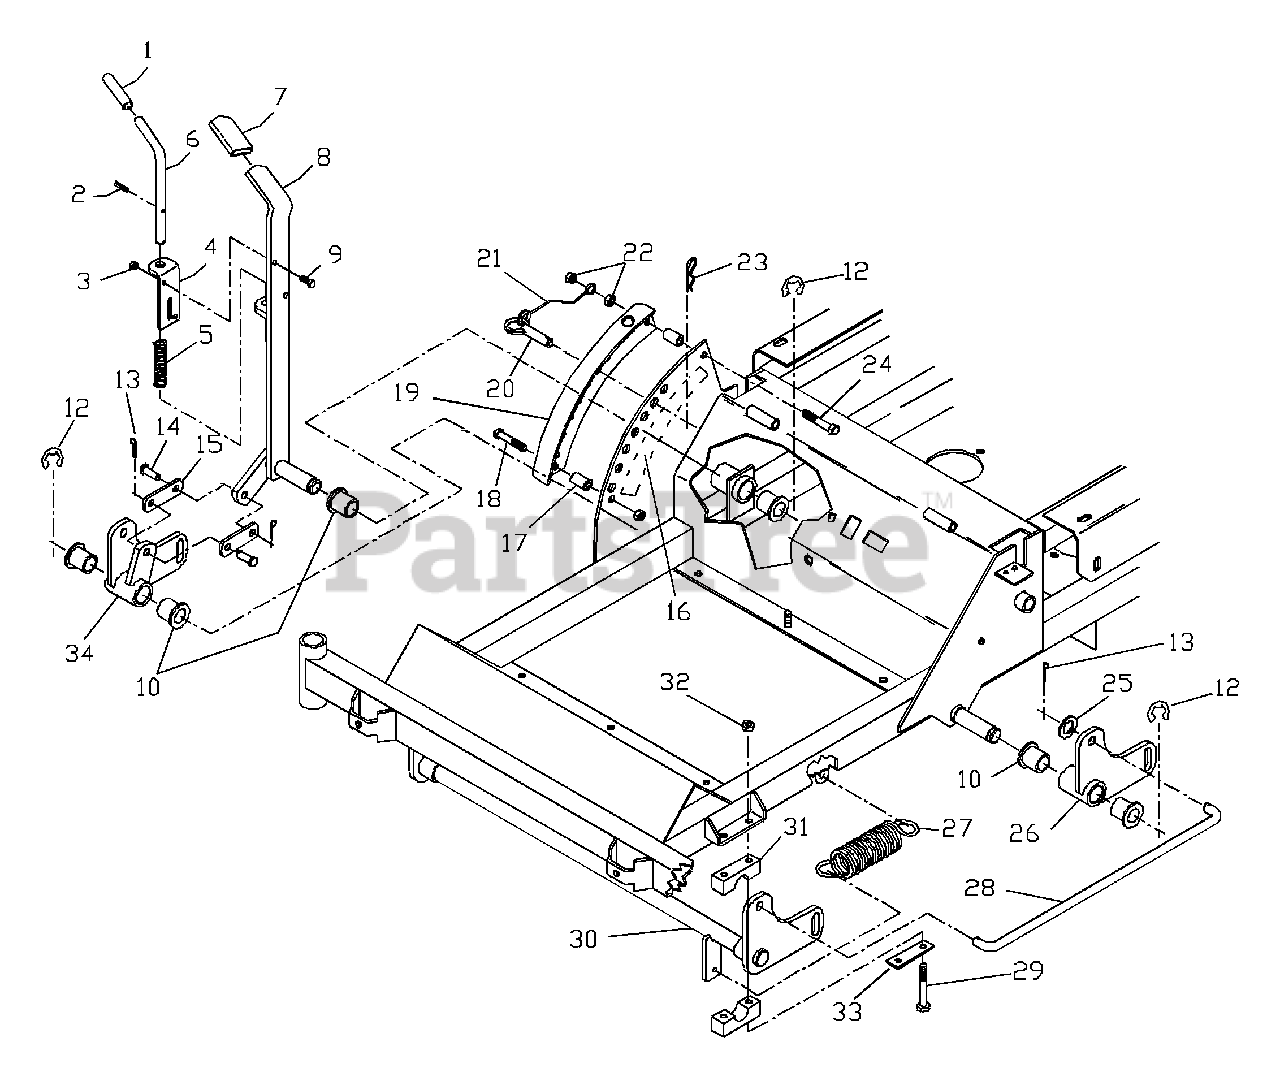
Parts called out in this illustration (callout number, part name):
2	3/16 X 1 ROLL PIN
3	NUT 1/4C CENTER LOCK
4	PIN MT, UPPER
8	LEVER WLDMT
9	1/4C X 3/4 HCS
10	FLANGED BUSHING
11	BELLCRANK WLDMT - RT
12	7/8 "E" RING
13	1/8 X 3/4 COTTER PIN
14	3/8 X 1 1/8 CLEVIS PIN
16	DECAL, LOCATOR
18	HCS 3/8C X 2
19	LOCATOR WLDMT
22	NUT 3/8C CENTERLOCK
23	#4 HAIRPIN
24	HCS 3/8C X 2 1/4
25	1/2 MACH. BUSHING
26	BELLCRANK WLDMT - LT
29	HCS 5/16C X 2 3/4
30	LIFT WLDMT
31	LIFT BLOCK
32	NUT 5/16C CENTERLOCK
33	REINF. PLATE
34	BELLCRANK WLDMT.
